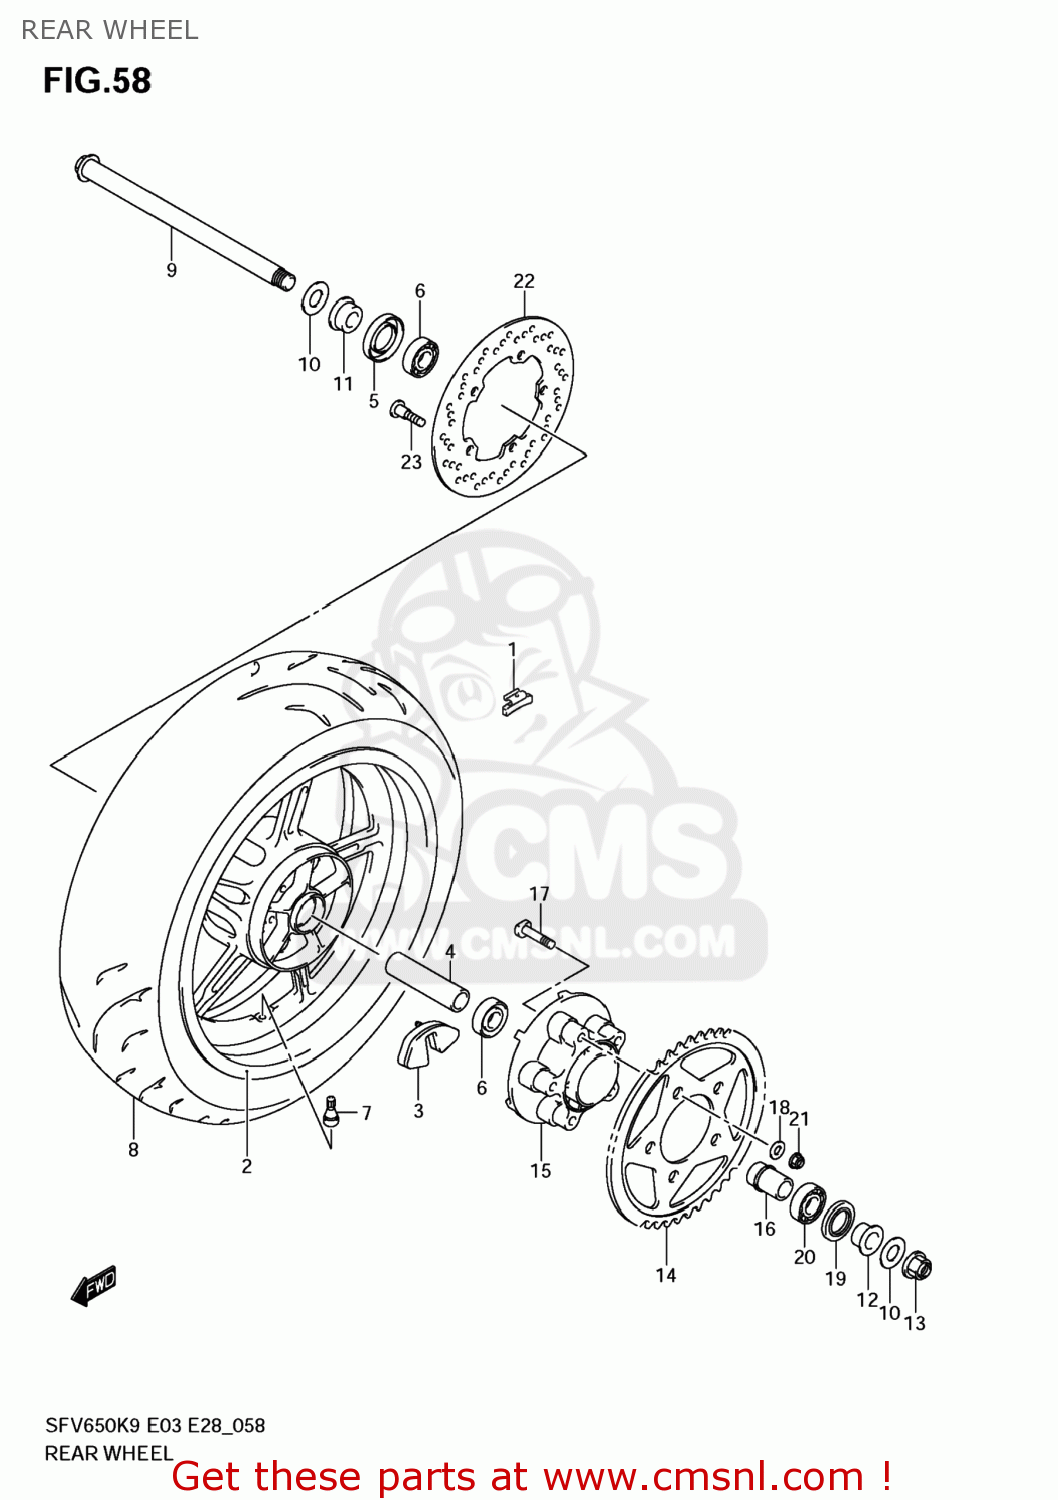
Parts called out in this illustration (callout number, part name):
1	BALANCER,WHEEL(10G)
2	WHEEL,RR(17M/CXMT5.00)
3	ABSORBER,RR HUB SHOCK
4	SPACER(20.5X28X88)
5	SEAL,OIL(28X47X7)
6	BEARING
7	VALVE ASSY,WHEEL RIM(TR412)
8	TIRE SFV650
9	AXLE,RR
10	WASHER,RR AXLE
11	SPACER,RR AXLE,R
12	SPACER,RR AXLE,L
13	NUT
14	SPROCKET,RR(46T-520)
15	DRUM,RR SPROCKET MOUNTING
16	RETAINER,RR HUB BEARING
17	BOLT(10X47)
18	WASHER(10.5X22X2.3)
19	SEAL,OIL(35X62X8)
20	BEARING(25X62X17)
21	NUT
22	DISC,RR BRAKE
23	BOLT(8X21)
